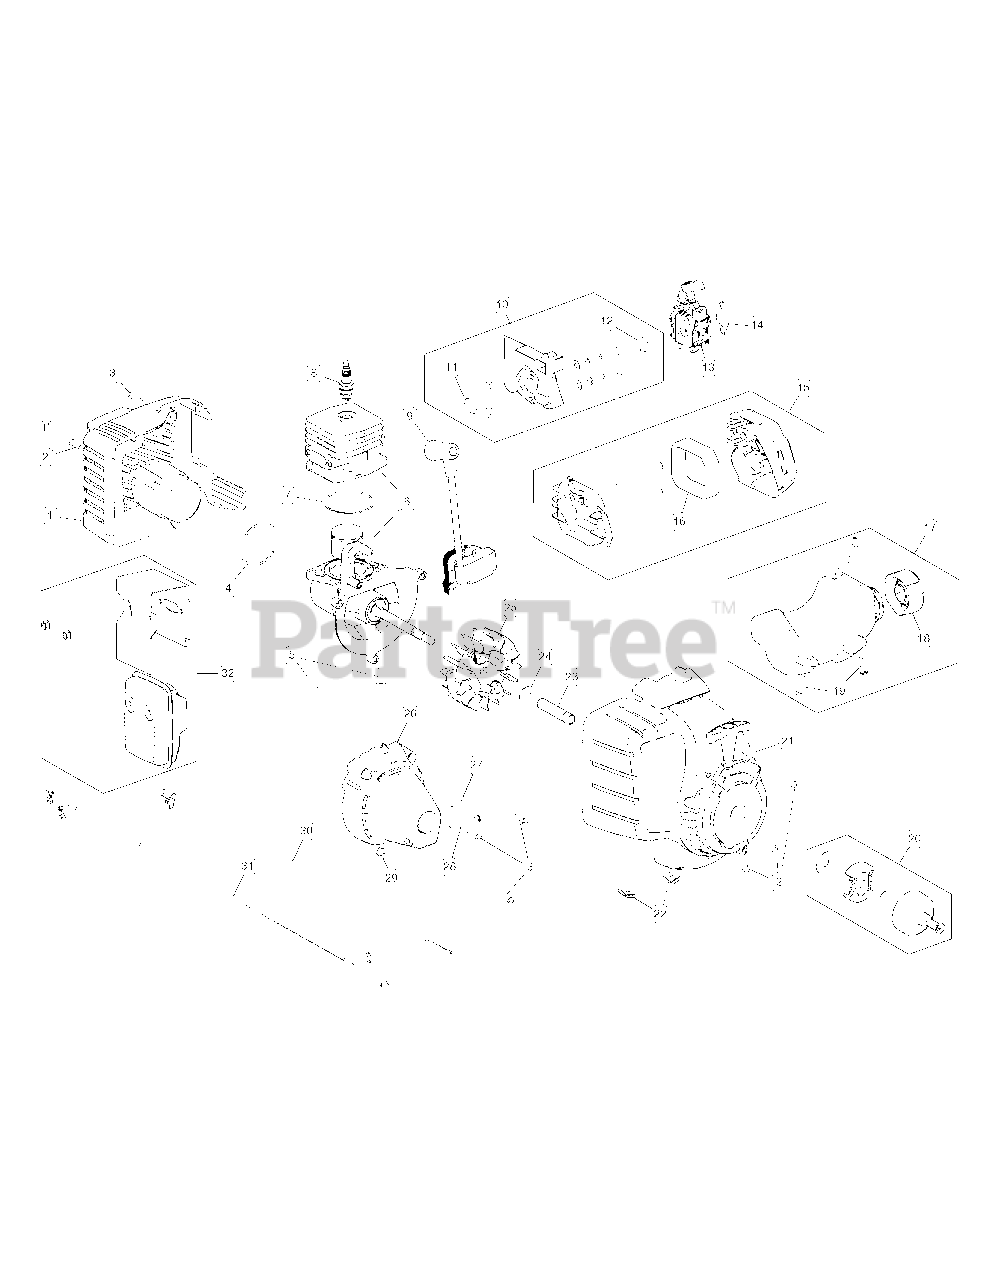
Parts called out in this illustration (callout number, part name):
1	Rear Cover Assembly (Incl. 2 & 34)
2	Rear Housing Screw
3	Cover Screw
4	O-Ring
5	Crankcase Bolt
6	Crankcase O-Ring
7	Short Block Assembly (Incl. 4 - 6, 8, 9 & 24 - 26)
8	Spark Plug
9	Module Assembly
10	Insulator Assembly (Incl. 11 & 12)
11	Insulator O-Ring
12	Carburetor O-Ring
13	Carburetor
14	Air Cleaner Gaske
15	Aircleaner Cover Assembly (Incl. 16)
16	Aircleaner Filter
17	Fuel Tank Assembly (Incl. 18 & 19)
18	Fuel Tank Cap
19	Fuel Tank Screw
20	Clutch Assembly
21	Starter Housing (Incl. 2 & 13)
22	U-shaped Nut
23	Spacer
24	Washer
25	Flywheel Assembly
26	Clutch Cover (Incl. 3)
27	Anti-rotation Screw
28	Clamp Screw
29	Clamp Nut
30	Throttle Cable
31	Lead Wires
32	Muffler Assembly
